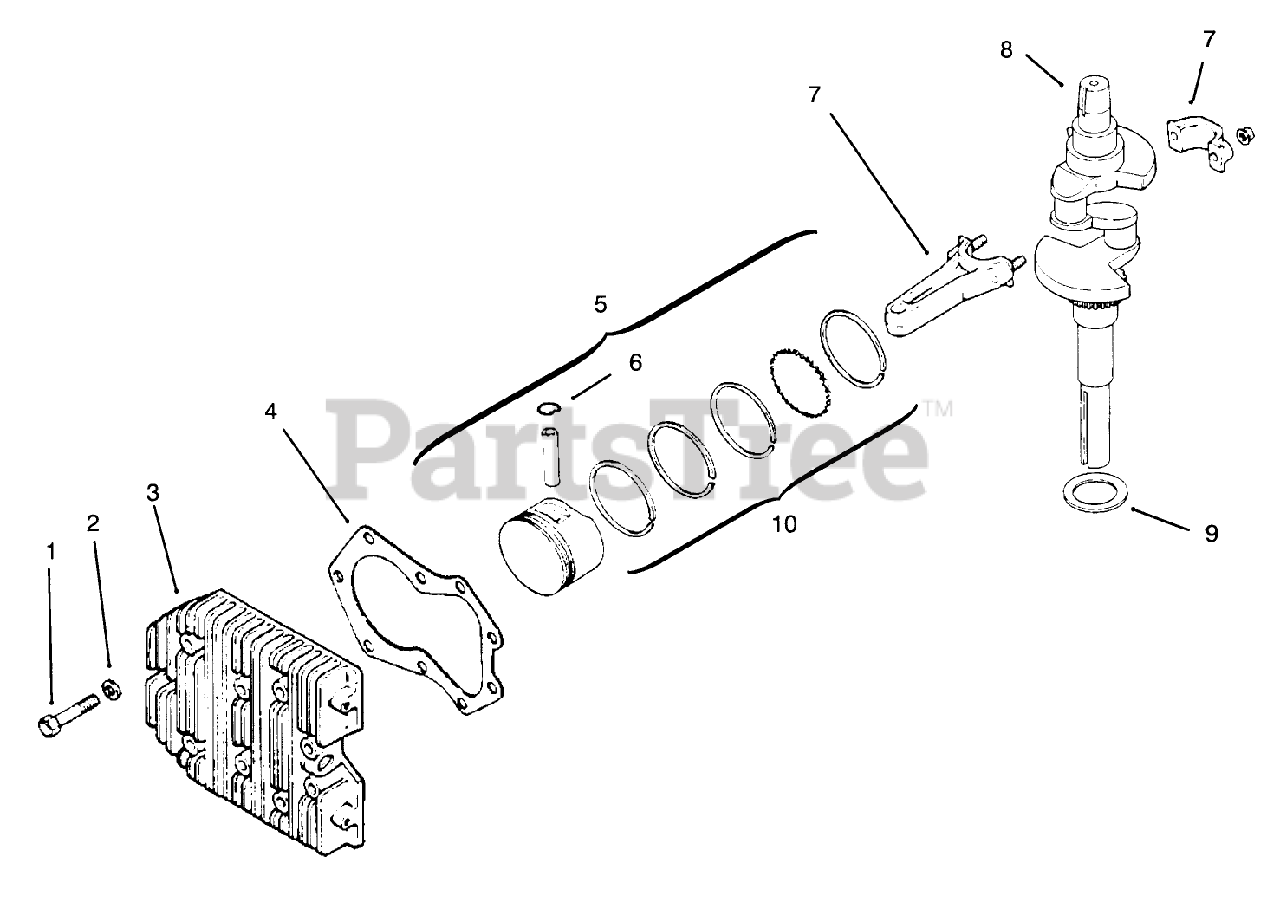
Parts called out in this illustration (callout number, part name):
1	Screw H.C.
2	Washer
3	Head-Cylinder
4	Gasket-Head
5	Piston Ring Set Std.
6	Retainer, Pin
7	Rod-Connecting Std.
8	Crankshaft
9	Washer-Thrust
10	Ring Set Std. .003"
